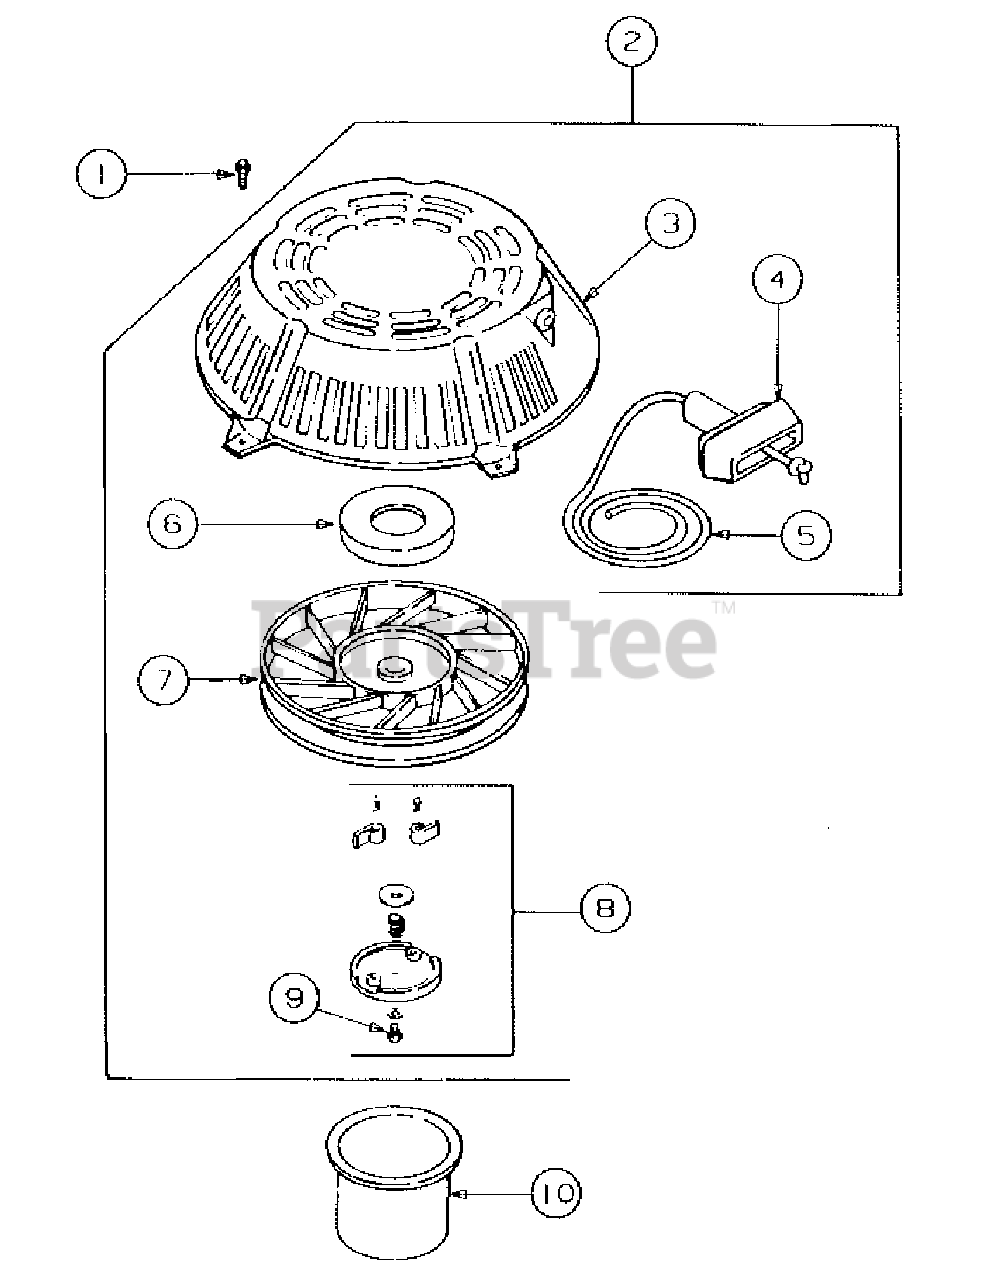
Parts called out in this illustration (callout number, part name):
1	Screw, M5 x 0.8 x 10
2	Starter, Retractable Ass'y
3	Housing, Starter
4	Handle, Recoil Start
5	Rope, Starter
6	Spring & Keeper
8	Kit, Pawl(dog)
9	Screw,Pozidriv
